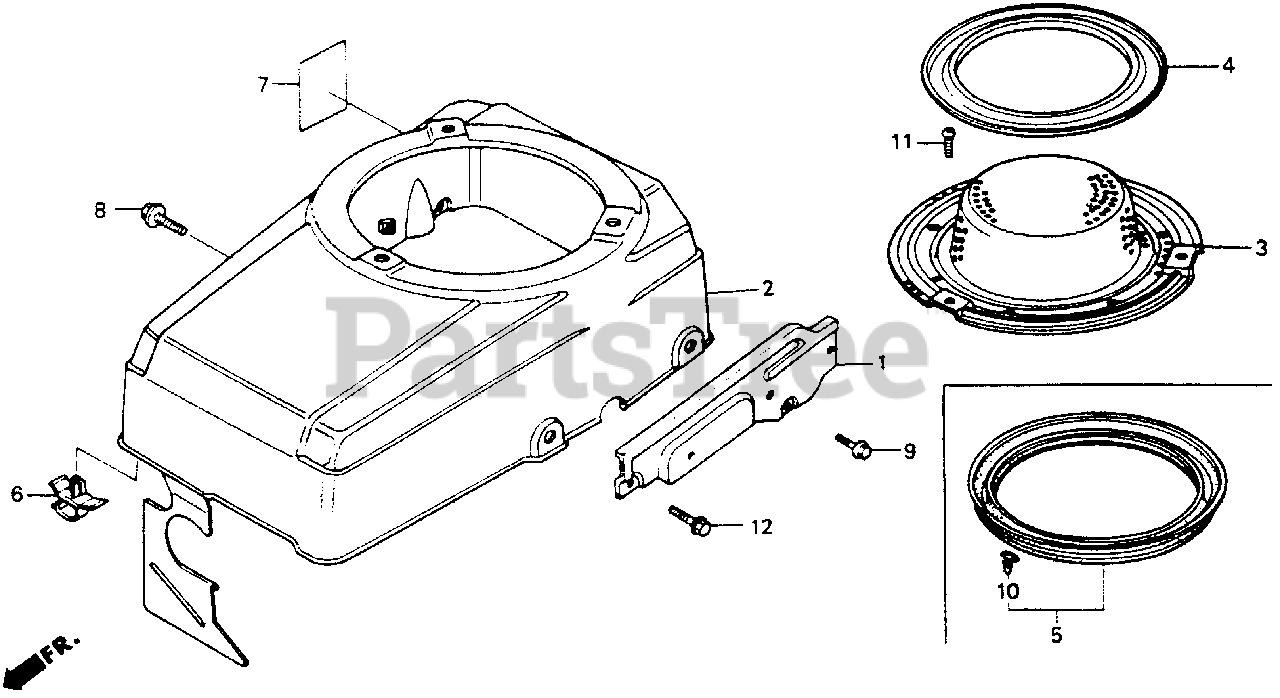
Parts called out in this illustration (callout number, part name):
1	STAY, TANK
2	COVER, FAN
3	COVER, LAWN
4	SEAL, LAWN COVER
5	SEAL, LAWN COVER
6	CLIP, WIRE HARNESS
7	MARK, OIL CAUTION
8	BOLT, FLANGE (6X12) (CT200)
9	BOLT, FLANGE (6X16)
11	SCREW, PAN (6X8)
12	BOLT, FLANGE (8X22)
